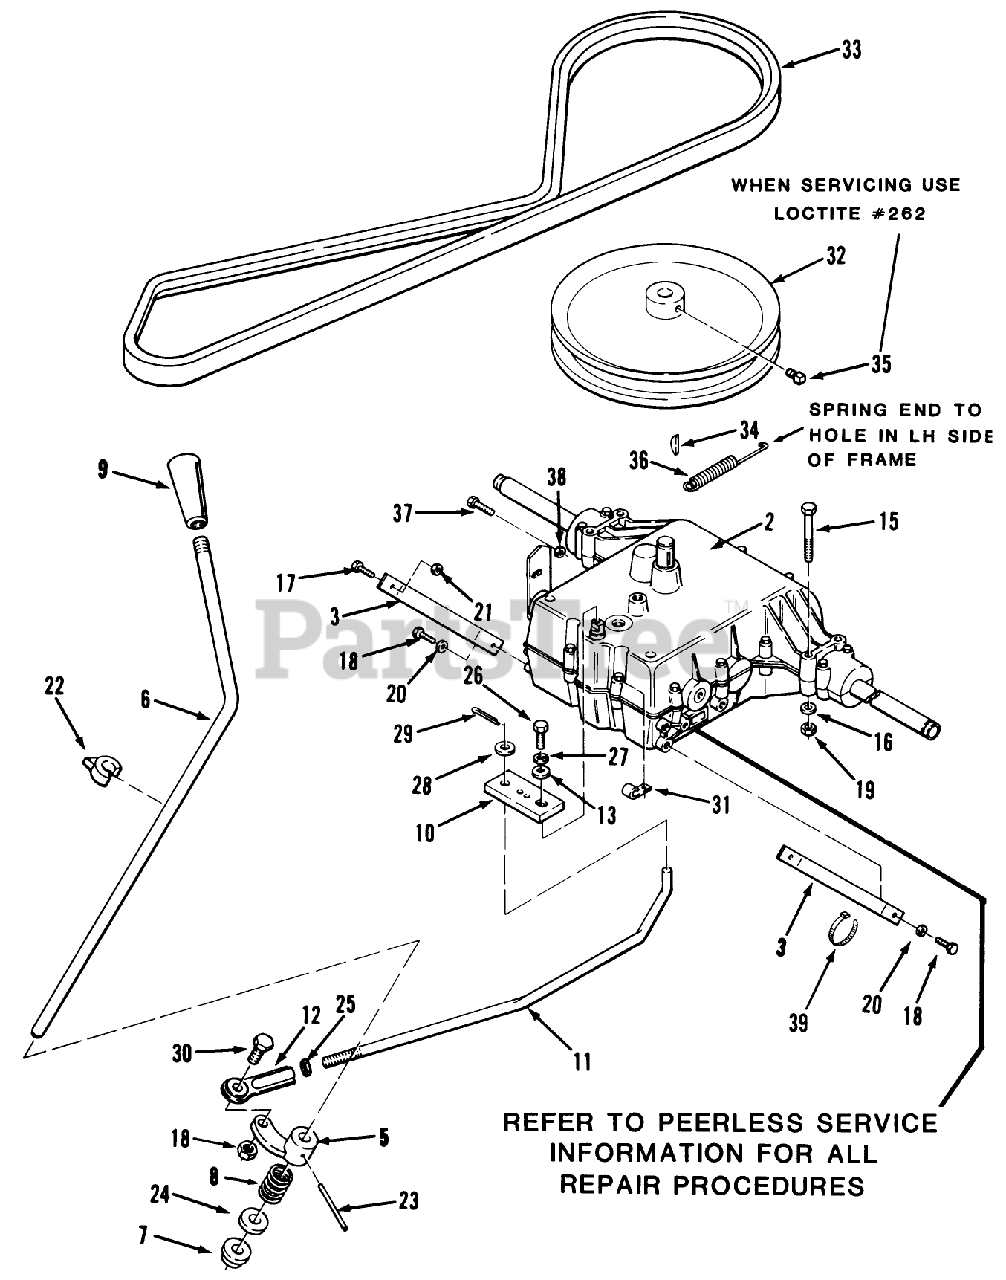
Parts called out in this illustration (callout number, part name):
2	Trans.-5-Spd.(Peerless Model 920-009)
3	TORQUE-STRAP R
5	ARM SHIFTER B
6	ROD-SHIFT LEVER
7	BUSHING-NYLINER
8	SPRING COMPRESSION
10	ARM-TRANSMISSION 5SP
11	ROD-LINKAGE
12	END-ROD
13	WASHER
15	HHCS
16	WASHER 5/16 SAE
17	CARRIAGE BOLT -4
18	Screw
19	Nut
20	Lockwasher
21	Nut
22	Pointer
23	SPIROL PIN 7/32X21/2
24	Washer
25	Nut
26	Hex Hd. Cap Screw 1/4-28 x 7/8
27	Washer
28	WASHER 5/16 SAE
29	Cotter Pin
30	BOLT-SPEC 5/16X1.25
31	J-CLIP
32	PULLEY-TRANS
33	BELT-V
34	KEY-HI-PRO
35	Set Screw
36	SPRING-EXTENSION
37	Bolt
38	Nut
39	PLASTIC TIE
